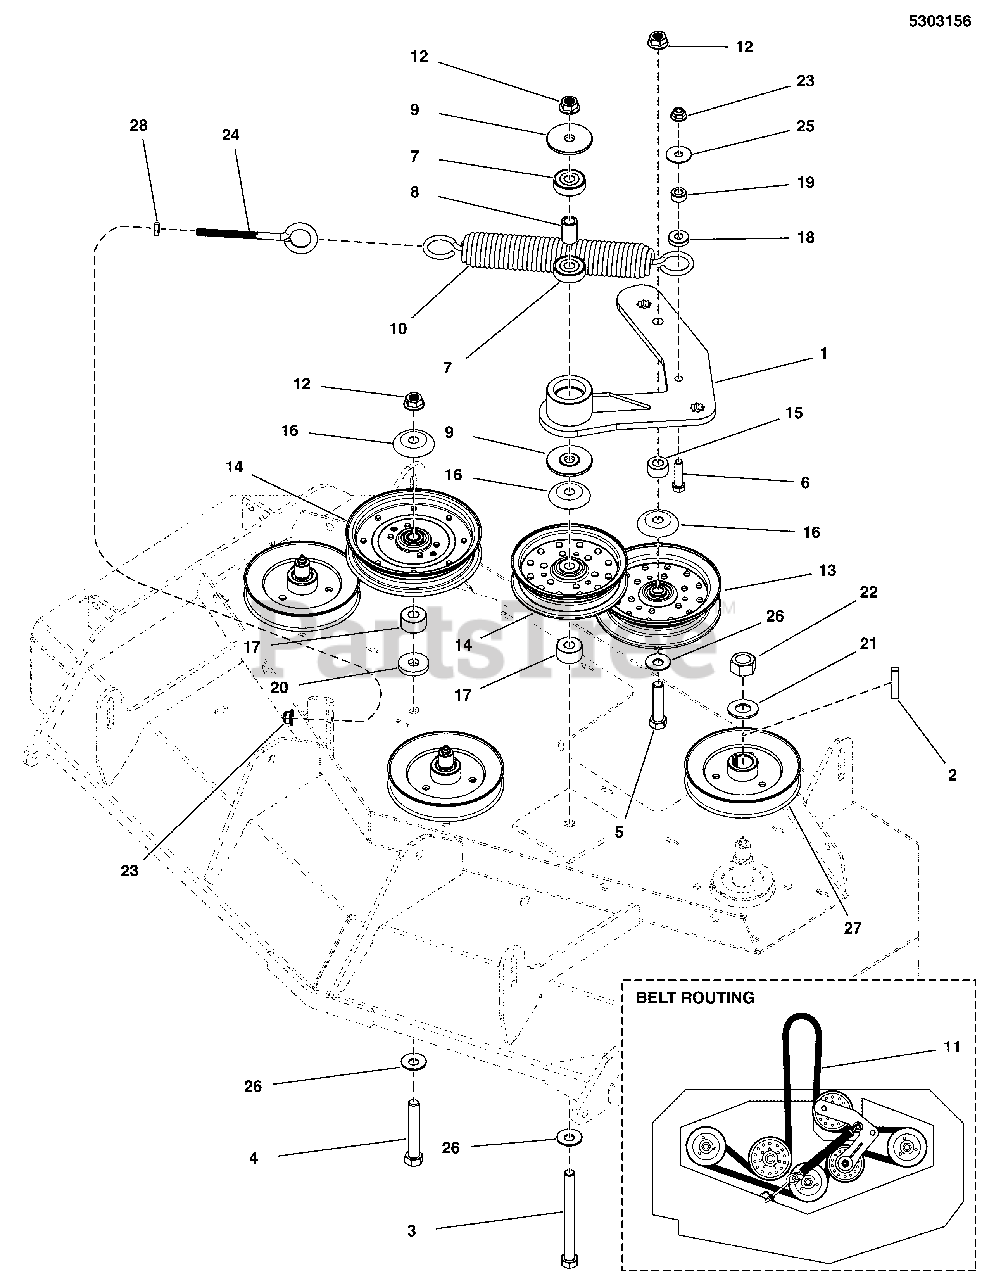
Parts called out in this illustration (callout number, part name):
1	WELD, IDLER ARM - BLK
2	KEY, 1/4 SQ X 1-1/4
3	BOLT, 1/2-13 X 5-1/2 GD5 CZ
4	BOLT, 1/2-13 X 2-3/4 GD5 CZ
5	BOLT, 1/2-13 X 2-1/2 GD5 CZ
6	BOLT, 3/8-16 X 1-1/2 GD5 CZ
7	BEARING, 6203-1/2", SEALED
8	SPACER, .51 X .75 X 1.22, PM, CZ
9	SPACER, IDLER ARM, 1/2 X 2.25
10	SPRING, EXT, 1.5ODX12.25X.234WIRE BLK
11	BELT, 5V, 158.90"EL, ARAMID WRPD, RC
12	NUT, 1/2-13 HEX NYLON LOCK
14	PULLEY, IDLER, 5" OD, 1"FACE, 5.75 FL
15	SPACER, .52 X 1.00 X .56, CZ
16	SHIELD, PULLEY BEARING, CZ
17	SPACER, .52 X 1.25 X .70, CZ
18	SPACER, .39 X 1.00 X .25
19	SPACER, .39 X .75 X .38
20	WASHER, .53 X 1.50 X .25
21	WASHER, 3/4 BELLEVILLE
22	NUT, 3/4-16 HEX
23	NUT, 3/8-16 HEX NYLOCK FLANGE
24	EYE BOLT, 3/8-16 X 5, 2.88THRD, 1EYE, CZ
25	WASHER-3/8 FENDER
26	WASHER, 1/2 SAE
27	PULLEY, 5.540OB X .985ID, SINGLE B-SEC
28	NUT, 3/8-16 HEX JAM
